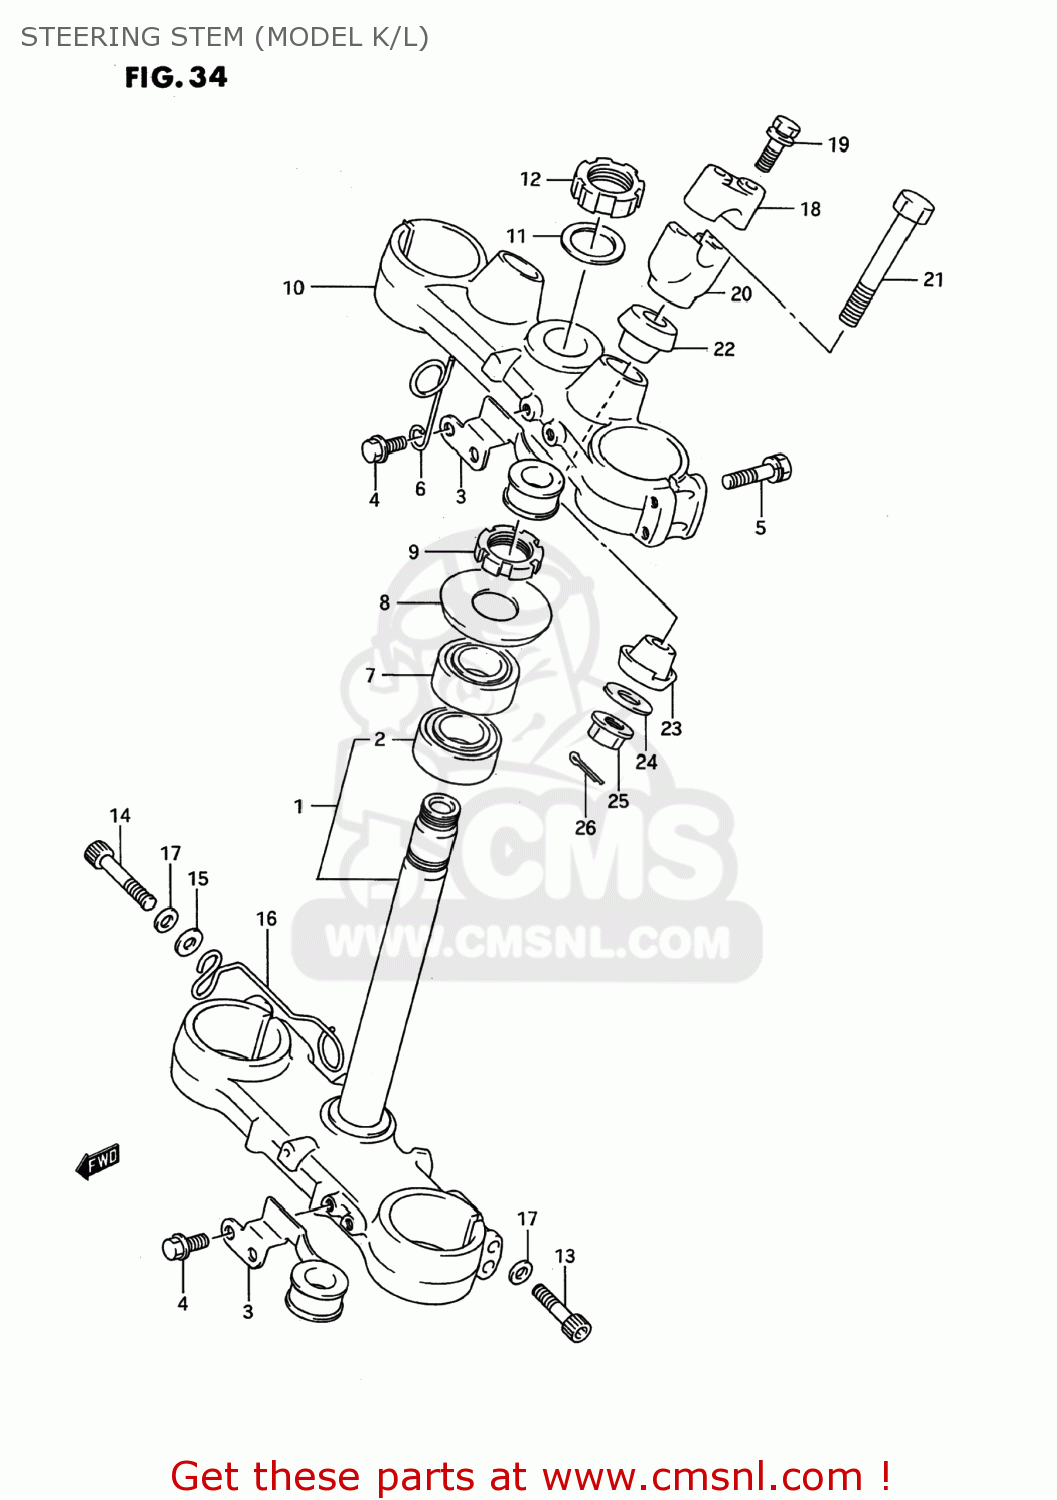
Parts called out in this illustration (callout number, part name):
1	STEM,STEERING
2	BEARING(28X54X16)
3	GUIDE,HOSE
4	BOLT
5	BOLT
6	CLIP,UPPER
7	BEARING
8	SEAL,STEERING,UPPER DUST
9	NUT,STEERING
10	STEM HEAD,STEERING
11	WASHER,STEM HEAD(24.5X34X1.6)
12	NUT,STEM HEAD
13	BOLT
14	BOLT, RH
15	WASHER
16	CLIP,LOWER
17	WASHER
18	HOLDER,HANDLEBAR
19	BOLT
20	HOLDER,HANDLEBAR
21	BOLT
22	DAMPER,UPR
23	DAMPER,LWR
24	WASHER,HANDLEBAR HOLDER
25	NUT
26	COTTER PIN
